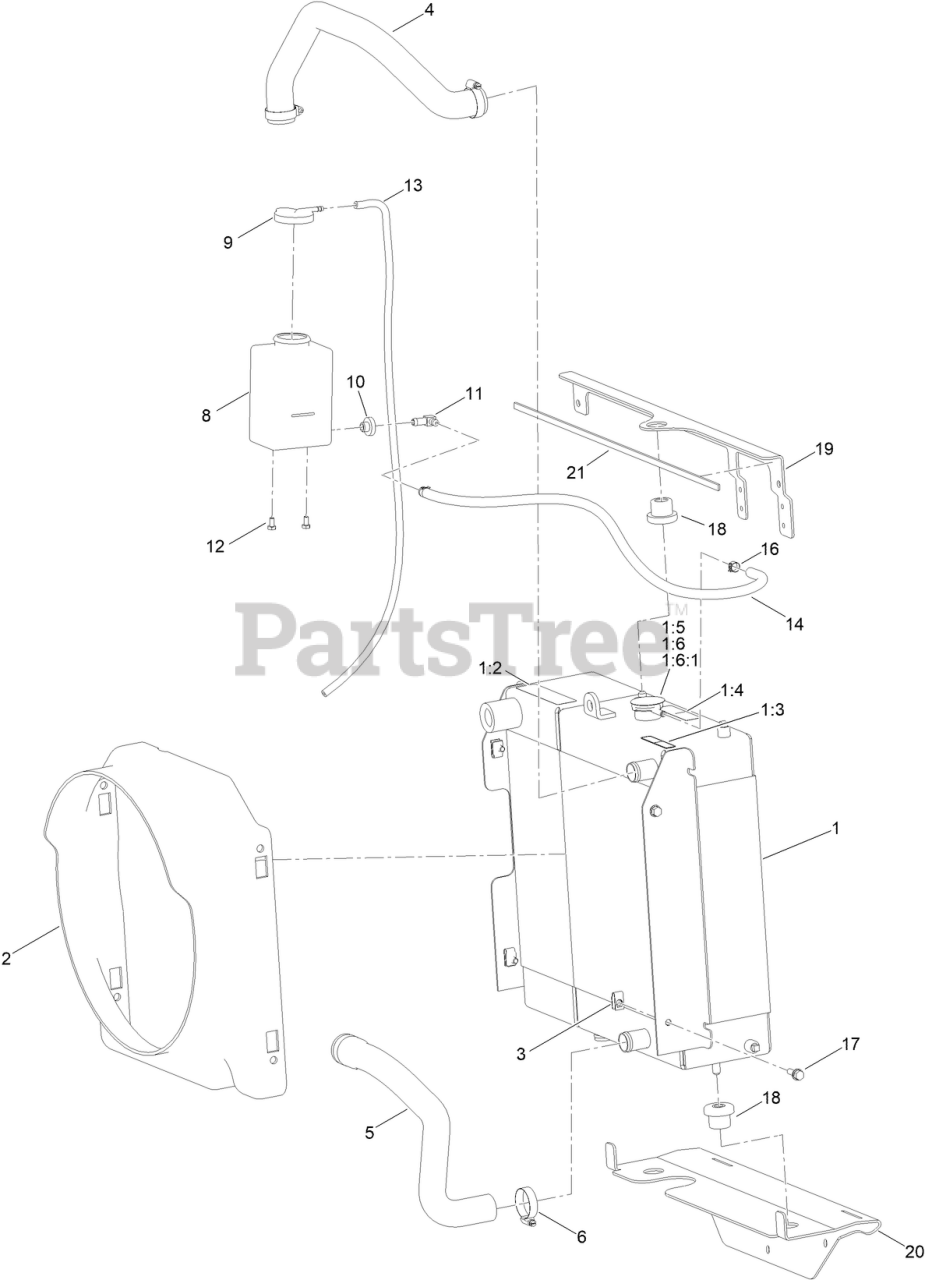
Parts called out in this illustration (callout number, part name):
1	COOLING ASM,
1:2	DECAL-DANGER
1:3	DECAL-WARNING, FAN
1:4	DECAL-RADIATOR FILL
1:5	DECAL-DANGER
1:6	CAP-RADIATOR
1:6:1	DECAL-DANGER
2	SHROUD-RADIATOR
3	NUT-CLIP, U
4	HOSE-RADIATOR
5	HOSE-RADIATOR
6	CLAMP-HOSE
8	TANK-OVERFLOW
9	CAP-TANK, OVERFLOW
10	BUSHING
11	FITTING-ELBOW, 90 DEG
12	SCREW-HH
13	HOSE-LP
14	HOSE-FUEL
16	CLAMP-HOSE
17	SCREW-HHF
18	MOUNT-ISOLATOR
19	BRACKET-COOLING, TOP
20	PLATE-COOLER
21	SEAL-FOAM
